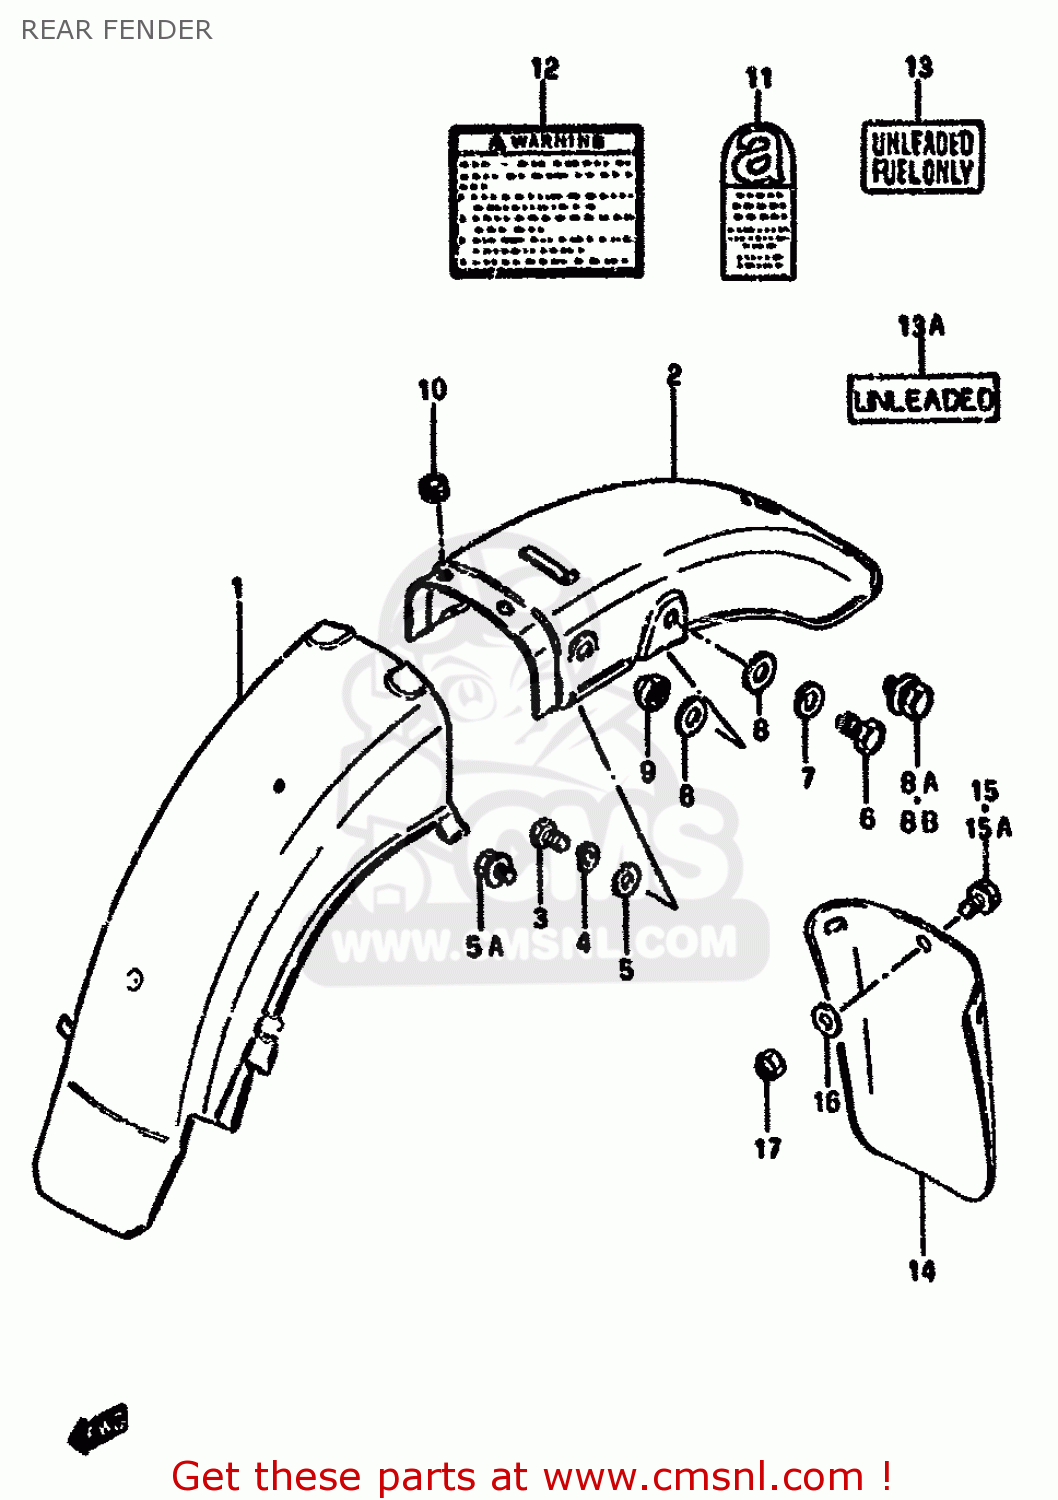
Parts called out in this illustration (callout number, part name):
1	BODY,FR
2	FENDER,REAR
3	BOLT
4	WASHER,LOCK
5	WASHER
5A	BOLT
6	BOLT
7	LOCK WASHER
8	WASHER
8A	BOLT
8B	BOLT
9	NUT
10	CUSHION
11	LABEL,ASBESTOS WARNING
12	LABEL, WARNING SAFETY
13	LABEL,FUEL CAUTION
13A	LABEL, CAUTION FUEL
14	FLAP,RR FENDER MUD
15	BOLT
15A	BOLT
16	WASHER
17	NUT 6MM
